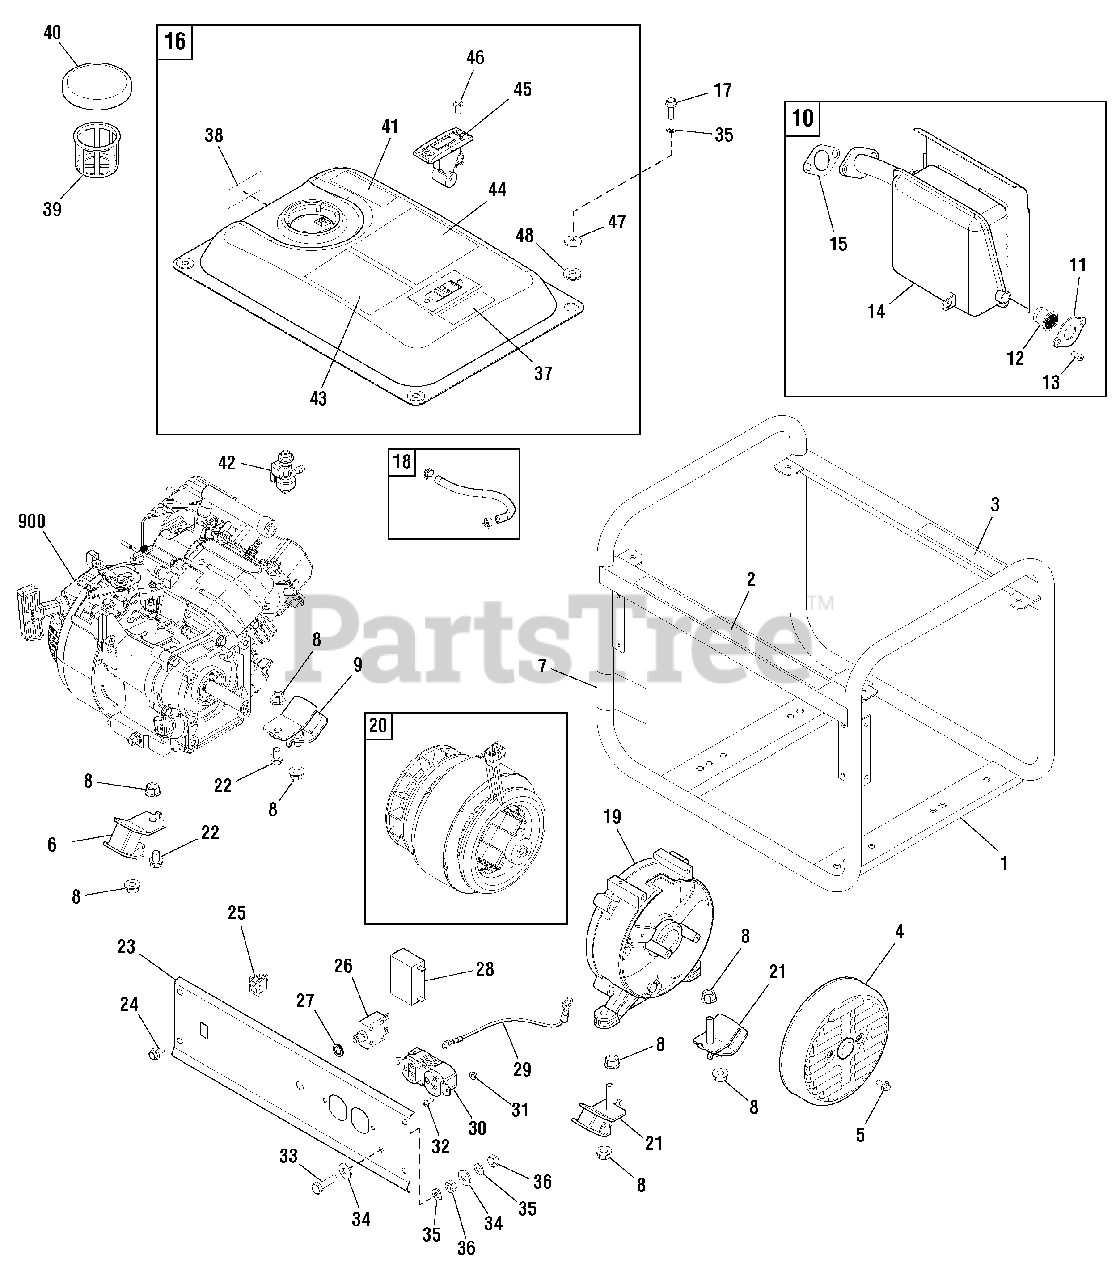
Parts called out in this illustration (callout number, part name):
5	* BOLT, M5 x 10
6	MOUNT-VIBRATION
8	* NUT, Flange, M8
9	MOUNT-VIBRATION
12	SPARK ARRESTOR
13	* SCREW, M5 x 12
15	GASKET-MUFFLER
17	* BOLT, M6 x 20
18	KIT-FUEL HOSE
19	CARRIER-BEARING
21	MOUNT-VIBRATION
22	* BOLT, M8 x 12
23	PANEL-CONTROL
24	* BOLT, M6 x 12
26	BREAKER-CIRCUIT
31	* NUT, Flange, M4
32	* SCREW, M4 x 14
33	* BOLT, M6 x 22
34	* WASHER, Flat, M6
35	* WASHER, Lock, M6
36	* NUT, M6
46	* SCREW, M5 x 10
48	MOUNT-VIBRATION
900	** ENGINE
